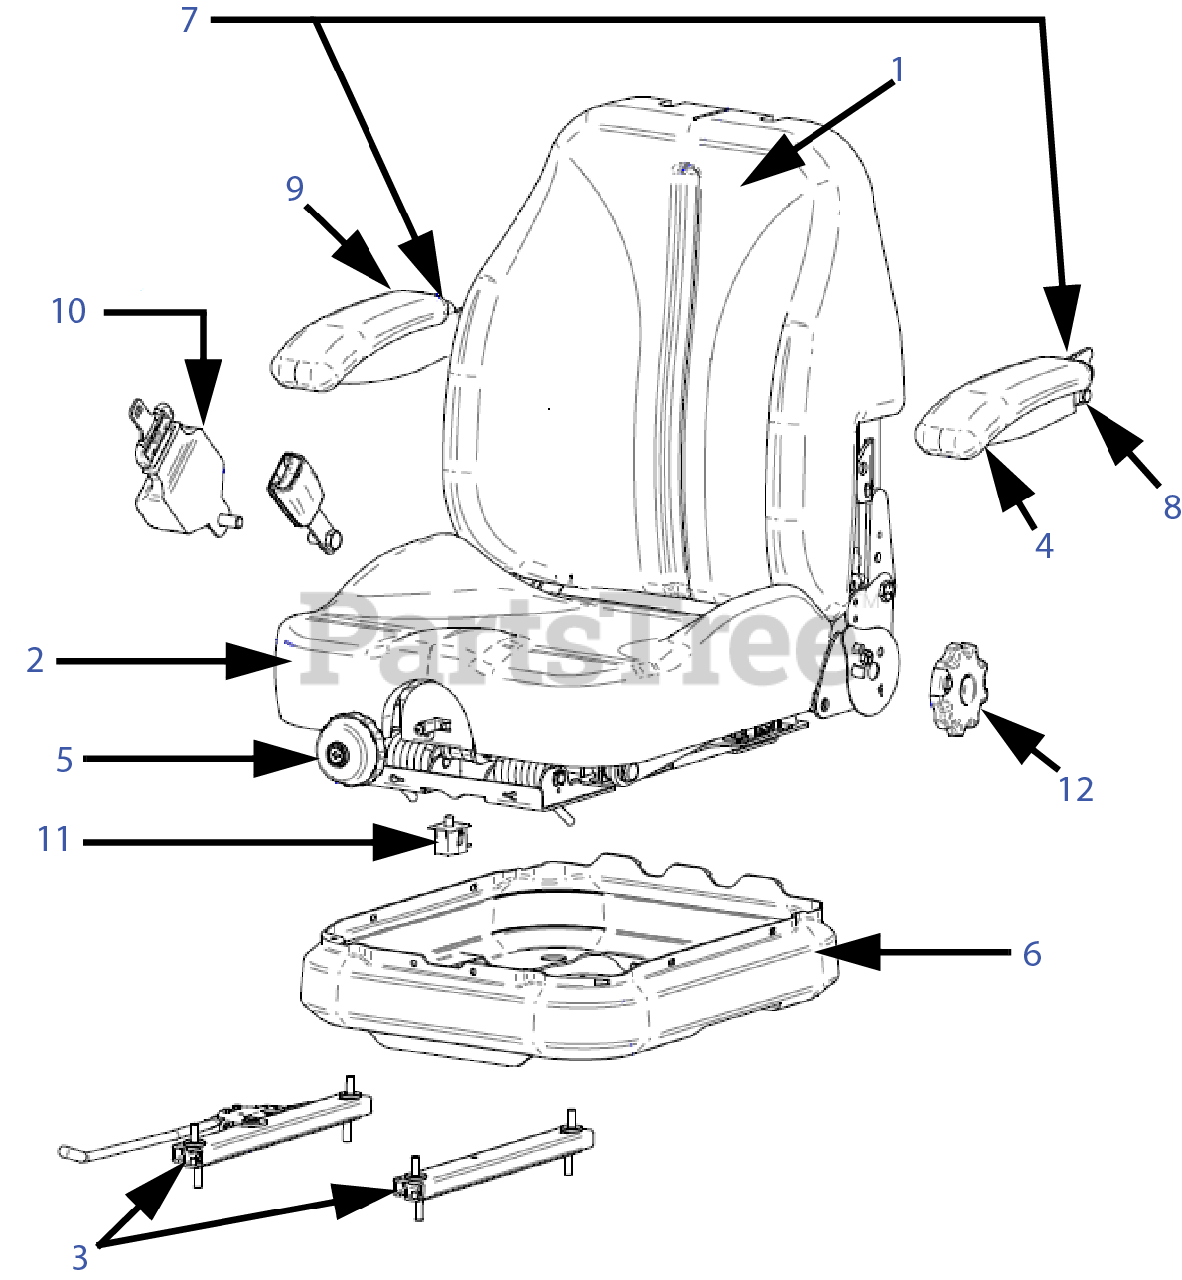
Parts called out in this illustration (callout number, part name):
1	BACK COVER WITH LOGO
3	7" SINGLE LOCKING TRACK KIT
4	BLACK SELFSKIN-ARM
5	KNOB ASSEMBLY-WEIGHT A
6	BELLOWS-W/HARDWARE
7	SET OF NON ADJUST ARMREST KIT
8	NON ADJUST ARMREST KIT (LH)
9	NON ADJUST ARMREST KIT (RH)
10	2" RETRACTABLE SEAT BELT KIT
11	PLUNGER SWITCH NC/NC
12	SEAT KNOB KIT
